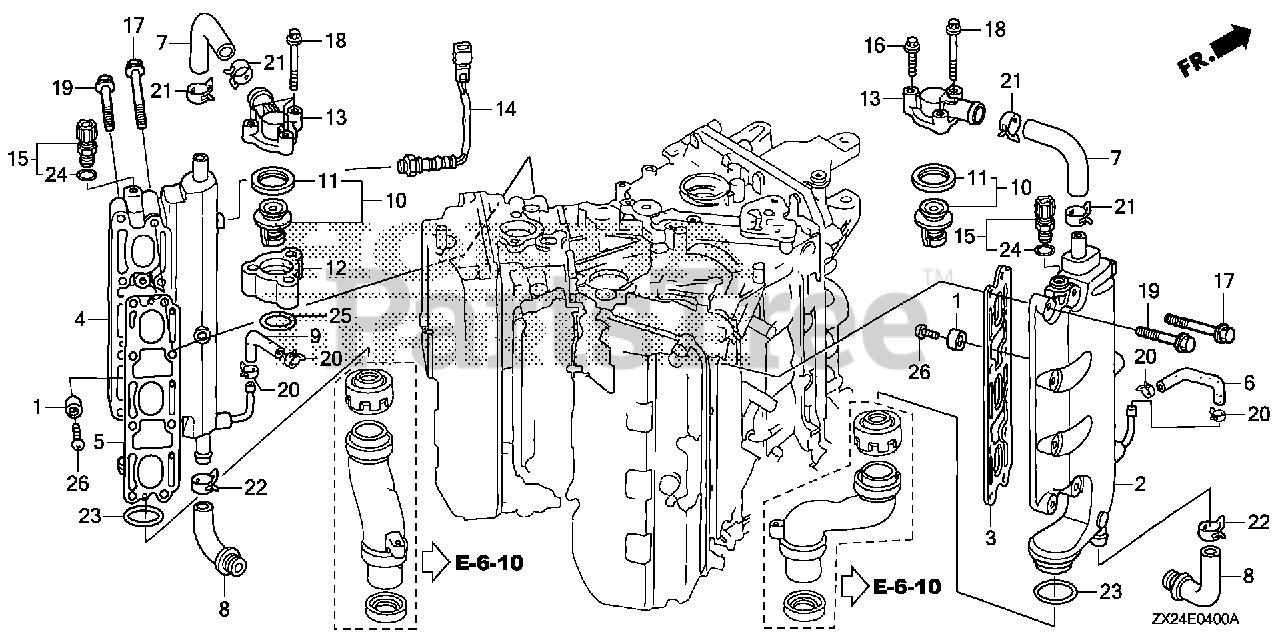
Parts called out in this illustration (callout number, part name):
1	METAL, ANODE
2	MANIFOLD, R. EX. *NH8* (DARK GRAY)
3	GASKET, R. EX. MANIFOLD
4	MANIFOLD, L. EX. *NH8* (DARK GRAY)
5	GASKET, L. EX. MANIFOLD
6	TUBE, R. WATER RETURN
7	TUBE, WATER RELIEF
8	TUBE, WATER
9	TUBE, L. WATER RETURN
10	THERMOSTAT ASSY.
11	RUBBER, RING
12	SPACER, THERMOSTAT COVER *NH8* (DARK GRAY)
13	COVER, THERMOSTAT *NH8* (DARK GRAY)
14	SENSOR, OXYGEN
15	SENSOR ASSY., WATER TEMPERATURE
16	BOLT, FLANGE (6X35)
17	BOLT, FLANGE (8X60)
18	BOLT, FLANGE (6X60)
19	BOLT, FLANGE (8X40)
20	CLAMP, TUBE (D10.5)
21	CLAMP, TUBE (D29)
22	CLAMP, TUBE (D21)
23	O-RING (66.4X3.1)
24	O-RING (9.5X1.9)
25	O-RING (31.5X2.4) (ARAI)
26	SCREW, PAN (6X18)
